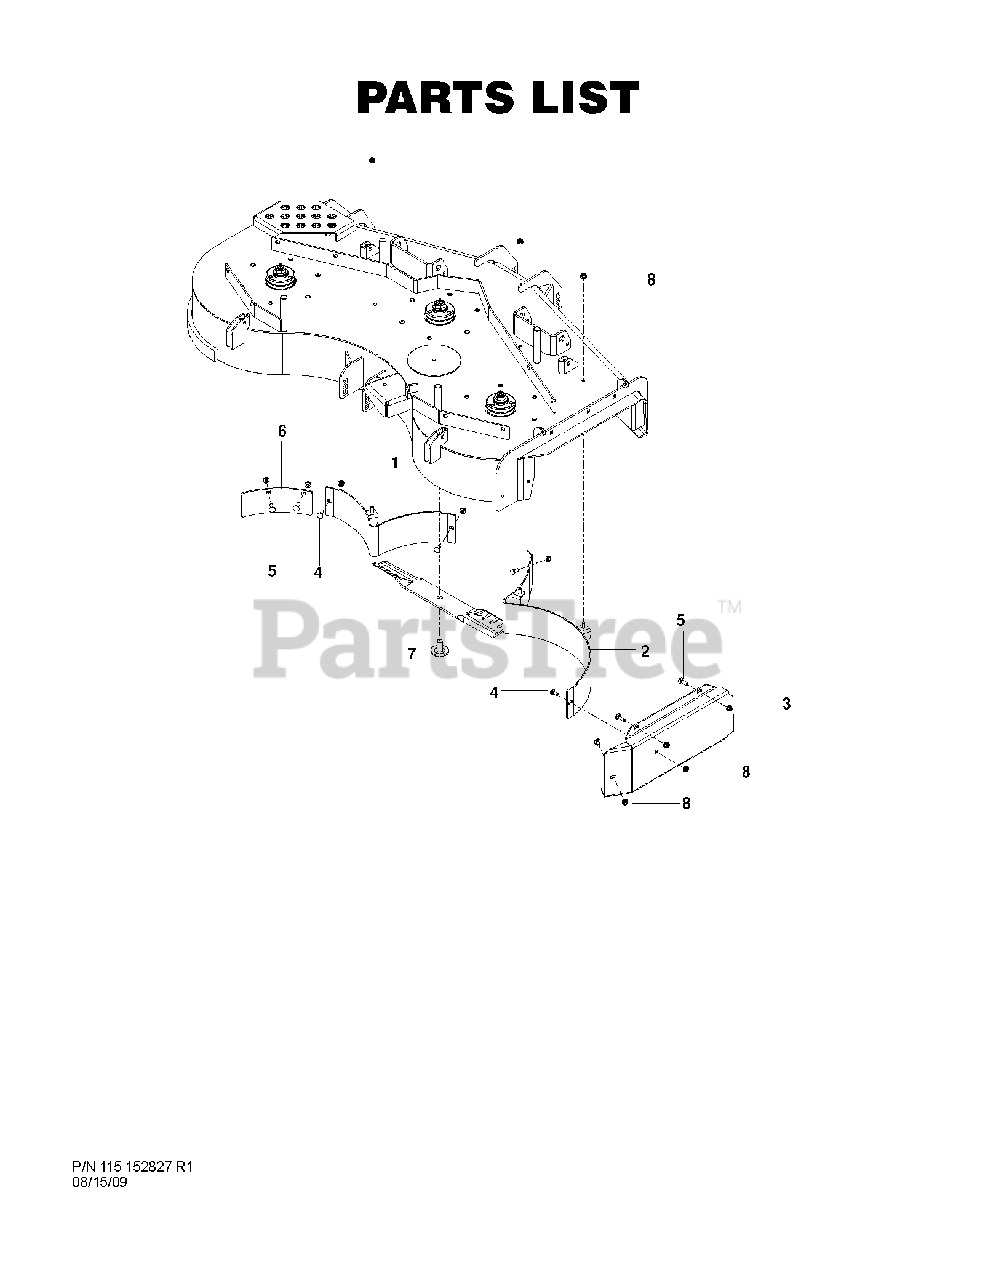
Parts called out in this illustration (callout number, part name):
1	MULCH BAFFLE 54" LH PAINTED
2	MULCH BAFFLE RH 54" BLACK
4	BOLT 5/16C X 3/4" CARRIAGE
5	RHSNB 5/16C X 1
6	Deck Baffle, 60" LH Corner
7	BLADE, 19" GATOR, 1.25" LIFT
8	5/16-18 NYLOC FLANGE NUT
